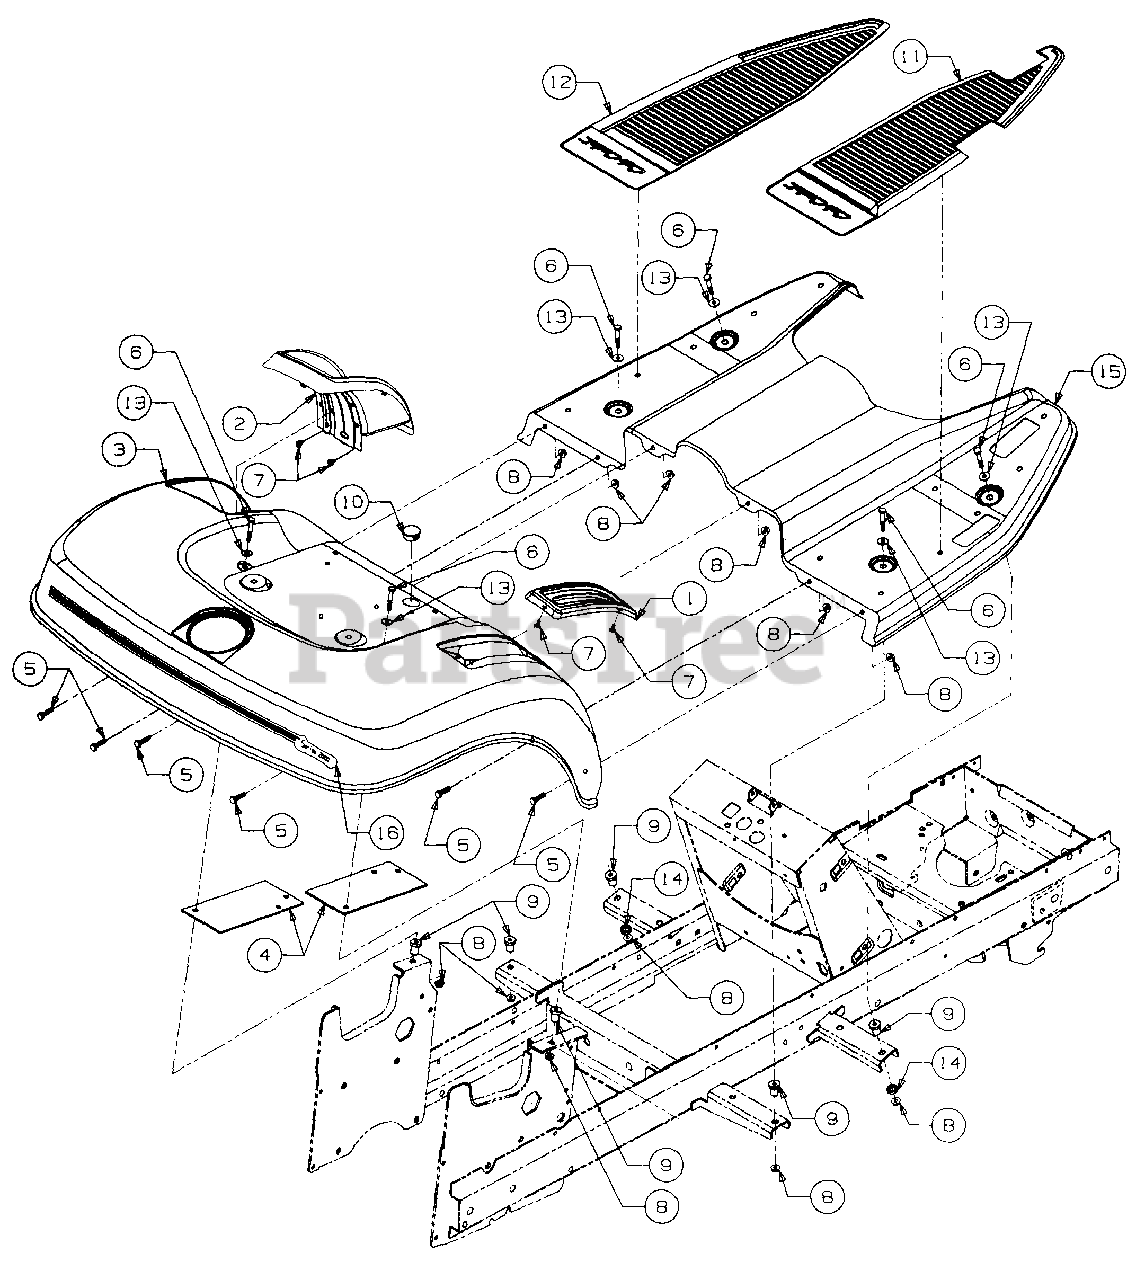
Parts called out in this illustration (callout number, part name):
1	Cover, Hydro Shifter
2	Cover, Implement Lift
4	Plate, Fender Reinforcement
5	Screw, Hex Cap, 1/4-20 x .62 Lg
6	Screw, Hex Cap, 1/4-20 x 1.5 Lg
7	Screw, Hex Tapp, #10 x .38 Lg
8	Nut, Hex Flange Lock, 1/4-20
9	Insolater, .50 OD x .88 Lg
10	Bushing, Snap, 7/8 ID
11	Pad, RH Foot
12	Pad, LH Foot
13	Washer, Flat, .255 x .720 x .060 Thk
14	Spacer, .511 ID x .70 OD x .38 Lg
15	Running Board w/Graphic
16	Graphic, Rear Fender
